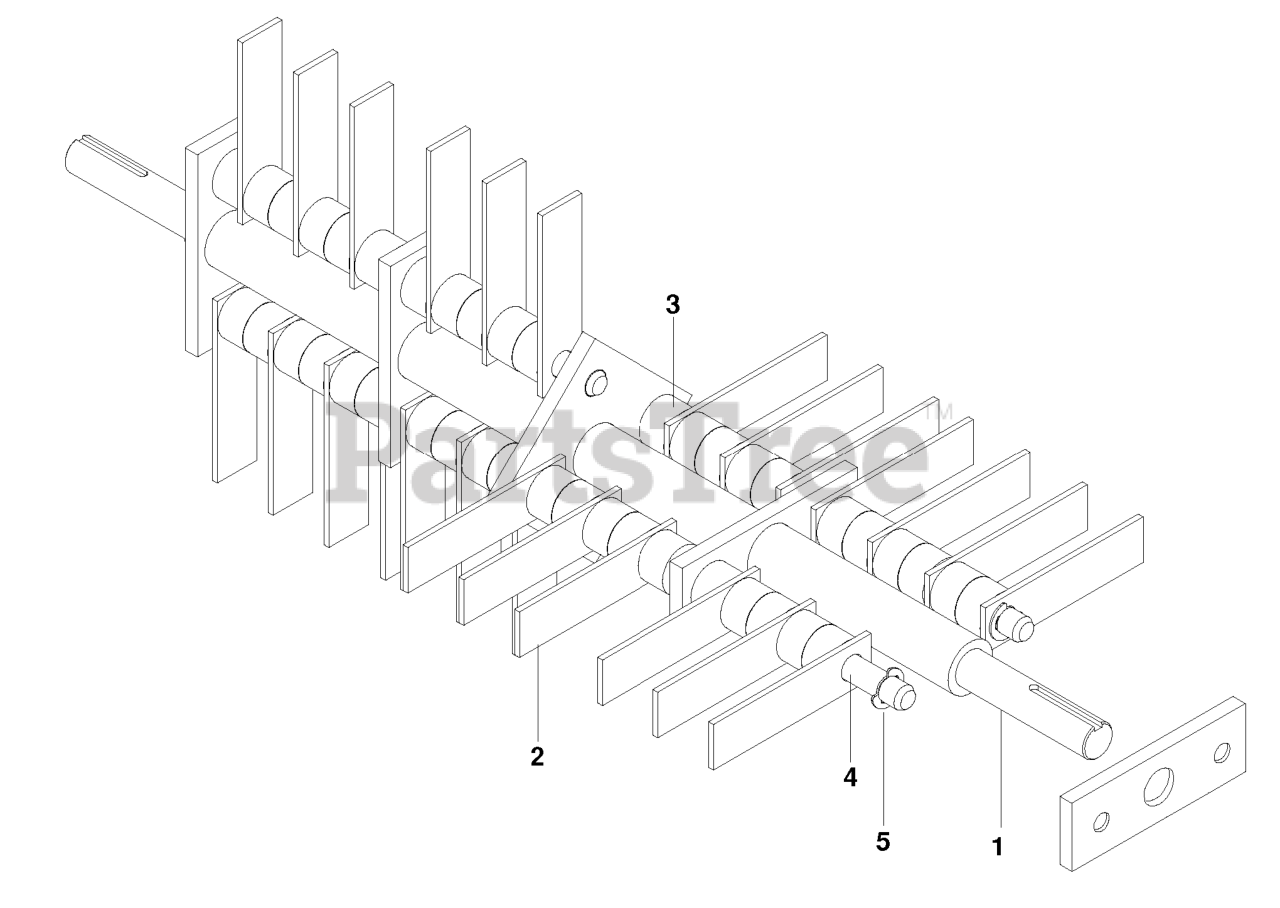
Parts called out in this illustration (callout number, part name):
3	SPACER 22"
4	BLADE SHAFT 22"
5	E-RING 1/2"
